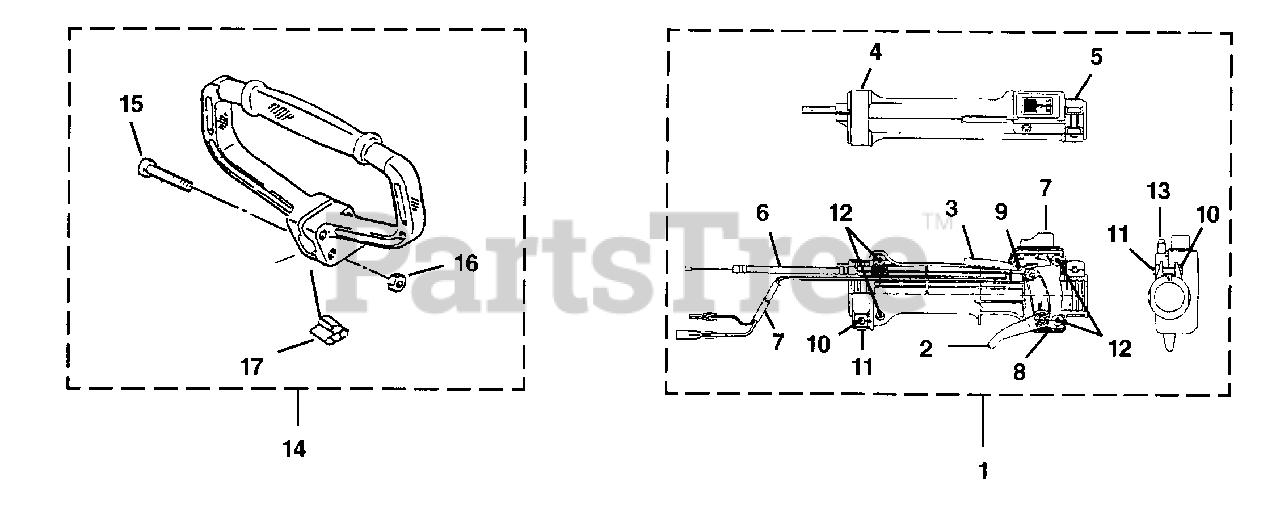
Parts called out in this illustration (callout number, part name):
1	CONTROL LEVER ASSEMBLY
2	THROTTLE-Trigger
3	LATCH-Trigger
6	CABLE-Throttle
7	SWITCH ASSEMBLY
10	SCREW
12	SCREW-Tapping
13	LOCK-Throttle Start
14	HANDLE ASSEMBLY
15	BOLT, Cross Recessed
16	NUT, Flange
